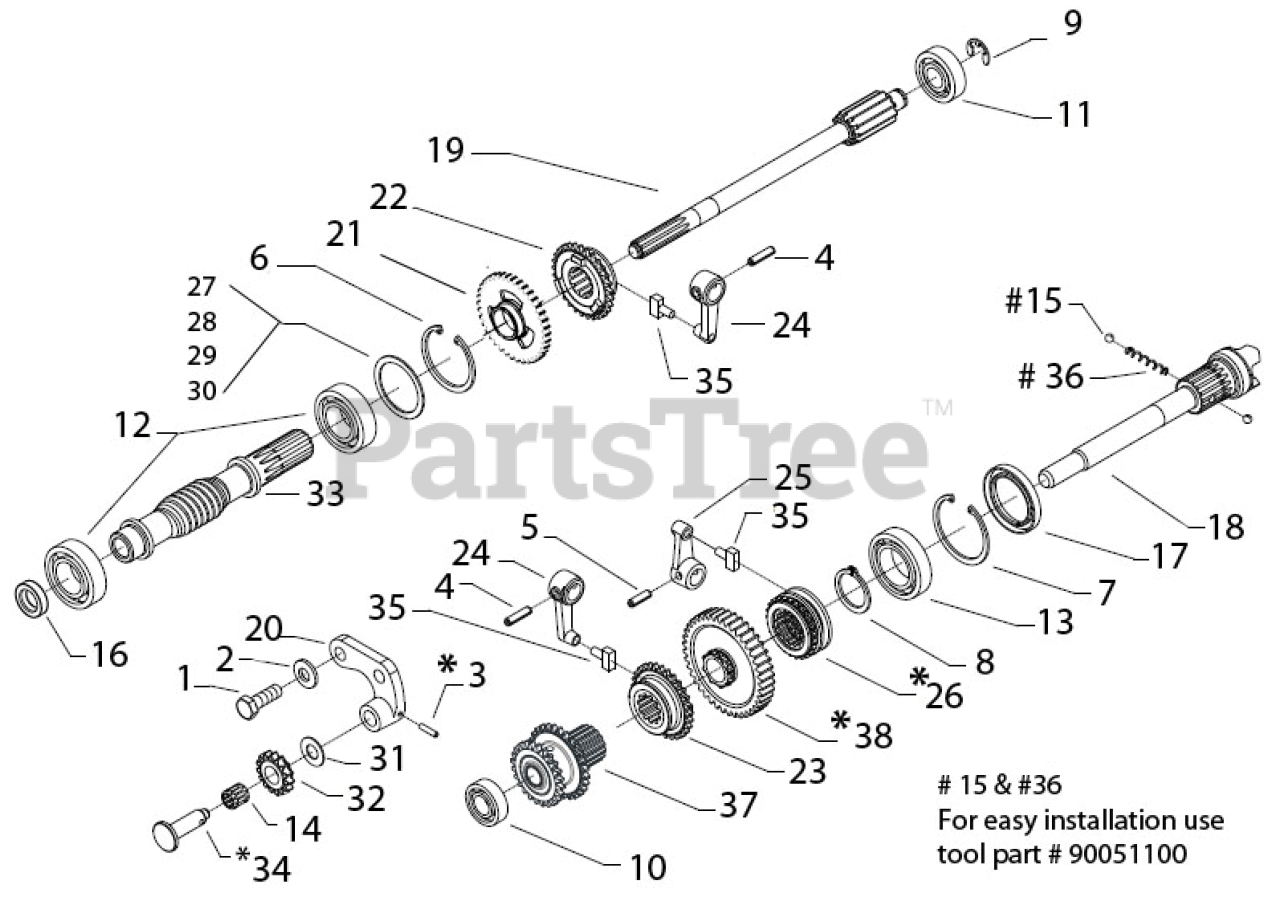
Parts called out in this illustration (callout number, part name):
1	SCREW TE M10X30 UNI 5739
2	WASHER M10
3	ROLL PIN M4X24
4	ROLL PIN M6X24
5	ROLL PIN M6X20 SPIRAL
6	SEEGER RING I 52 DIN 472
7	SEEGER RING I 55 DIN 472
8	SEEGER RING E 30 UNI 7436
9	SEEGER RING E 12 UNI 7434
10	BEARING M15X35X11
11	BEARING M15X42X13
12	BEARING M25X52X15
13	BEARING M30X55X13
14	BEARINGM 12X15X10
15	BALL 1/4
16	OIL SEAL 15X28X7
17	OIL SEAL 38X55
18	PTO SHAFT
19	MAIN INPUT SHAFT
20	REVERSER BRACKET
21	FIRST GEAR
22	SLIDER GEAR
23	PTO SLIDER
24	LEVER SLIDER
25	LEVER PTO ENGAGEMENT
26	PTO SLIDER
27	SHIM 1.5 MM
28	SHIM 1.6 MM
29	SHIM 1.7 MM
30	SHIM 1.8 MM
31	ADJUSTING RING
32	REVERSER GEAR
33	WORM GEAR
36	SPRING FOR PTO BALLS
37	DOUBLE GEAR
38	PTO GEAR
38	PTO KIT CONSISTS OF *26 & *38
